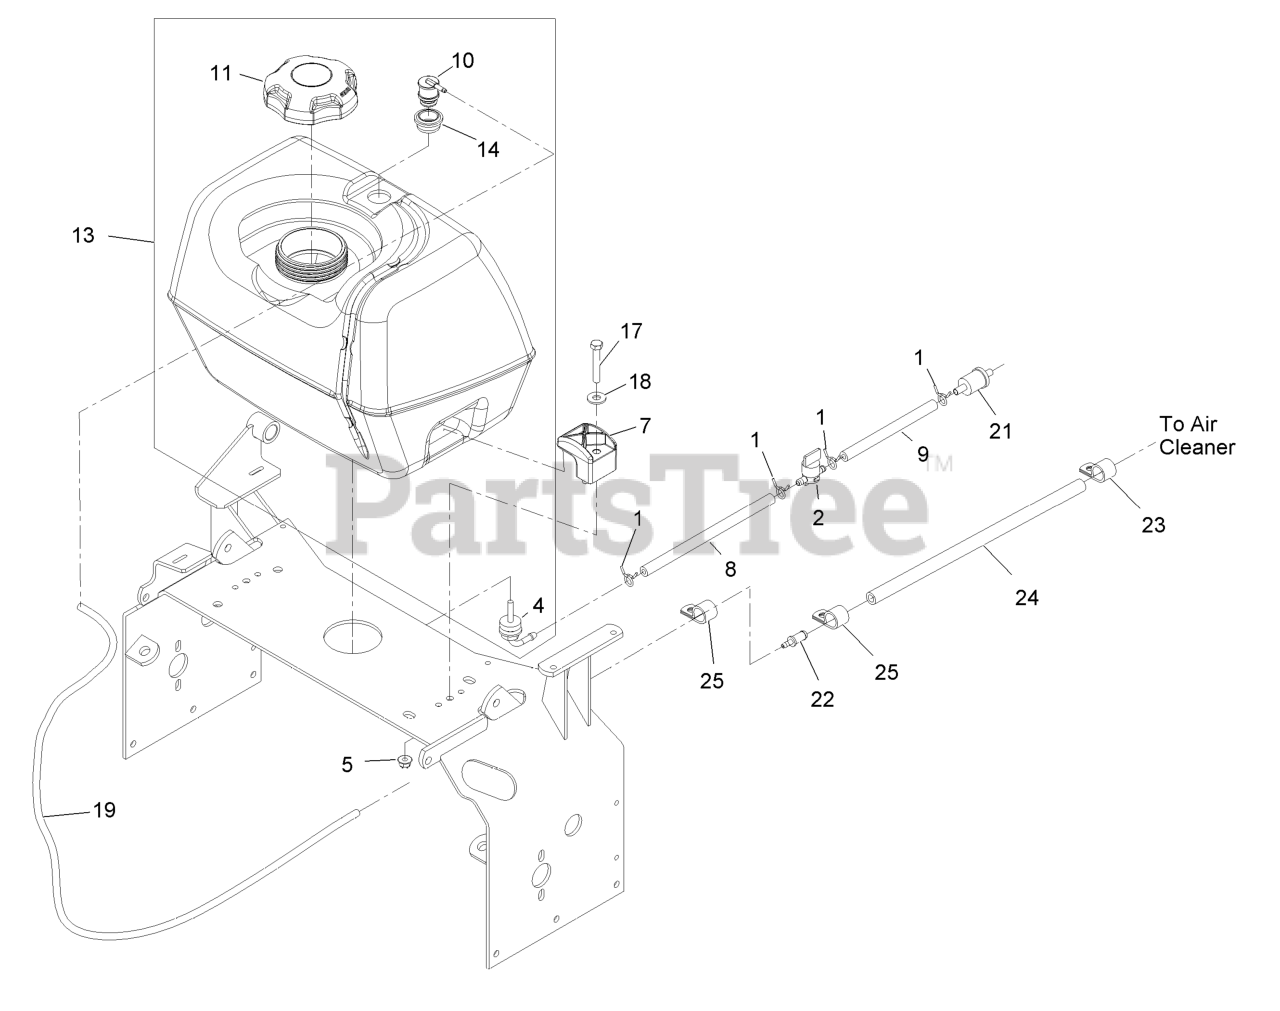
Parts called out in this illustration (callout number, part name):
2	VALVE-FUEL
4	FITTING-FUEL, BULKHEAD
5	NUT-HF, NI
8	HOSE-FUEL
9	HOSE-FUEL
17	SCREW-HH
18	WASHER-FLAT
19	HOSE-VENT
21	Pn 240513-S Filter-Fuel
22	FITTING-STRAIGHT
23	CLIP-LOOM
24	HOSE-FUEL
25	CLIP-LOOM
